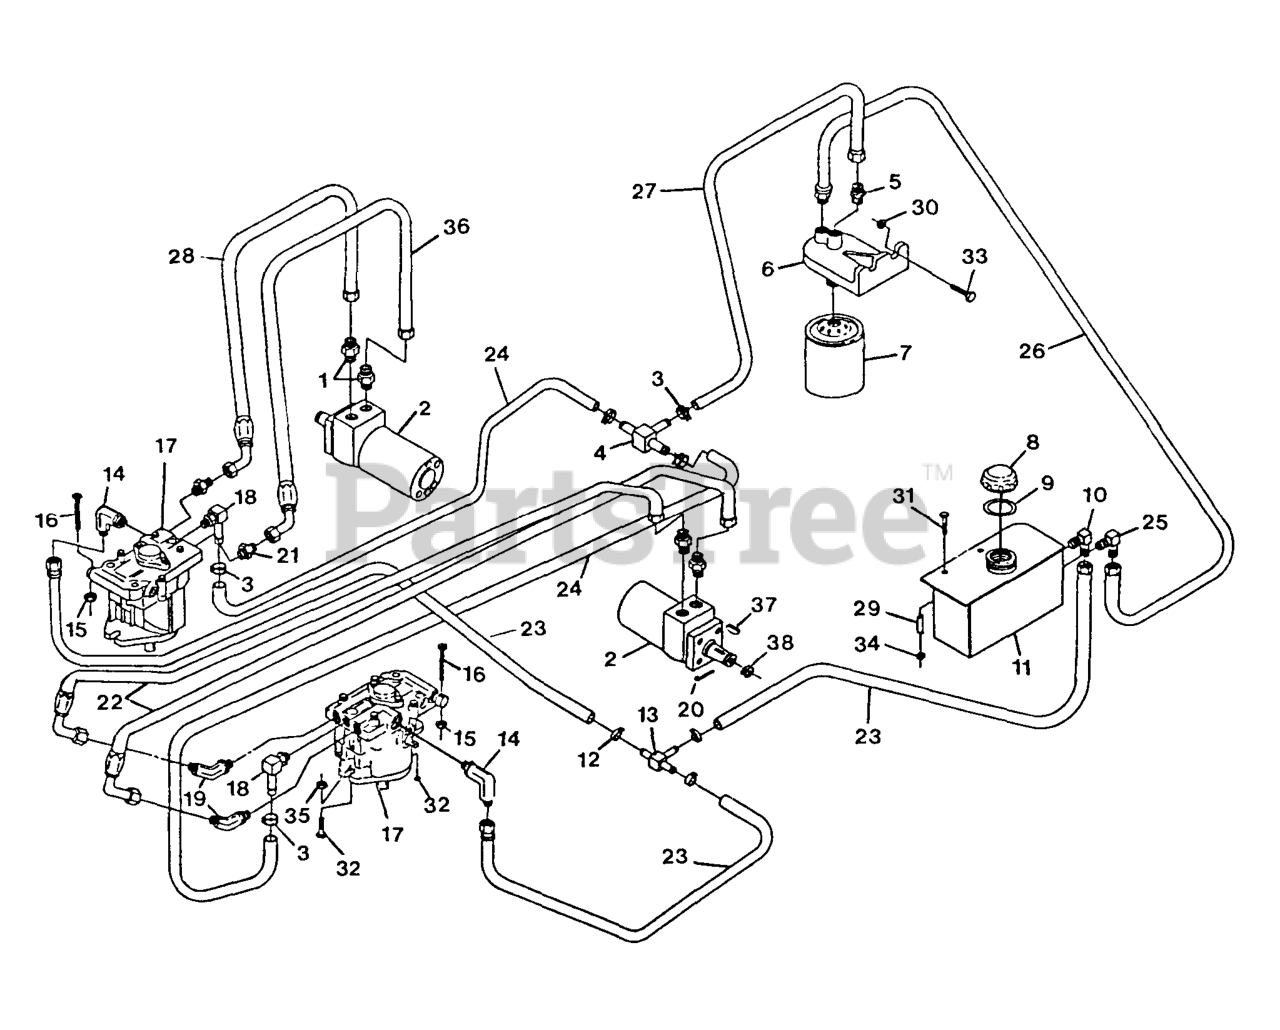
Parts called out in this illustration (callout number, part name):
1	FITTING-STRAIGHT
2	HYD MOTOR ASM
3	CLAMP-HOSE
4	FITTING-TEE, HOSE
5	FITTING-STRAIGHT
9	GASKET-CAP, TANK
10	FITTING-ELBOW
12	CLAMP-HOSE
13	FITTING-TEE, HOSE
14	FITTING-90 DEG
18	FITTING
19	FITTING-HYD, 45 DEG
20	PIN-COTTER
21	FITTING-STRAIGHT
22	HOSE-PRESSURE, HIGH
23	ASM,HOSE CASE DRAIN
25	FITTING-ELBOW
26	ASM,HOSE LO PRESSURE
27	ASM,HOSE CHARGE LINE
37	KEY-WOODRUFF
